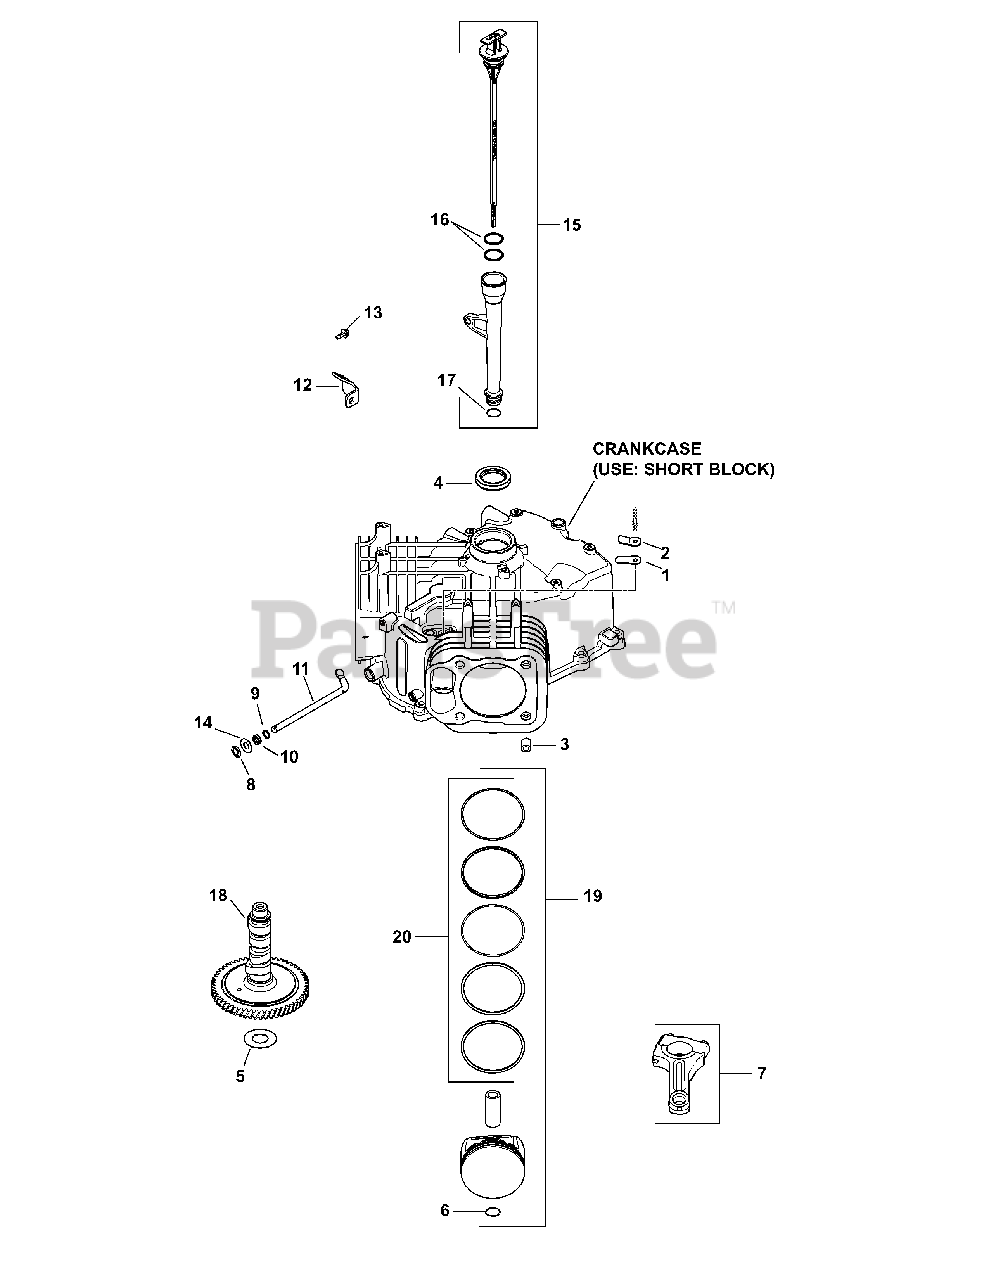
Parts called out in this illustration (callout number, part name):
1	Breather Reed
2	Breather Reed Retainer
4	Oil Seal (Helix Lip)
5	Camshaft Shim (White .028")
5	Camshaft Shim (Blue .03")
5	Camshaft Shim (Red .032")
5	Camshaft Shim (Yellow .034")
5	Camshaft Shim (Green .036")
5	Camshaft Shim (Gray .038")
5	Camshaft Shim (Black .04")
6	Piston Pin Retainer
7	Connecting Rod (Std)
8	Ring Retainer
9	Flat Washer, 11/32
10	Governor Cross Shaft Seal
11	Governor Cross Shaft
12	Oil Fill Tube Bracket
13	Flg. Thd. Frm. Screw, M5 x 0.8 x 13
14	Flat Washer, 9mm
15	Dipstick And Tube Kit
16	Dipstick O-Ring
17	O-Ring, Lower Oil Fill Tube
18	Camshaft Assembly
19	Piston w/ Ring Kit
19	Piston W/ Ring Kit (0.25) 83mm
19	Piston W/ Ring Kit (0.08) 83mm
20	Piston Ring Set, (Std)
20	Ring Set (.08)
20	Ring Set (.25)
